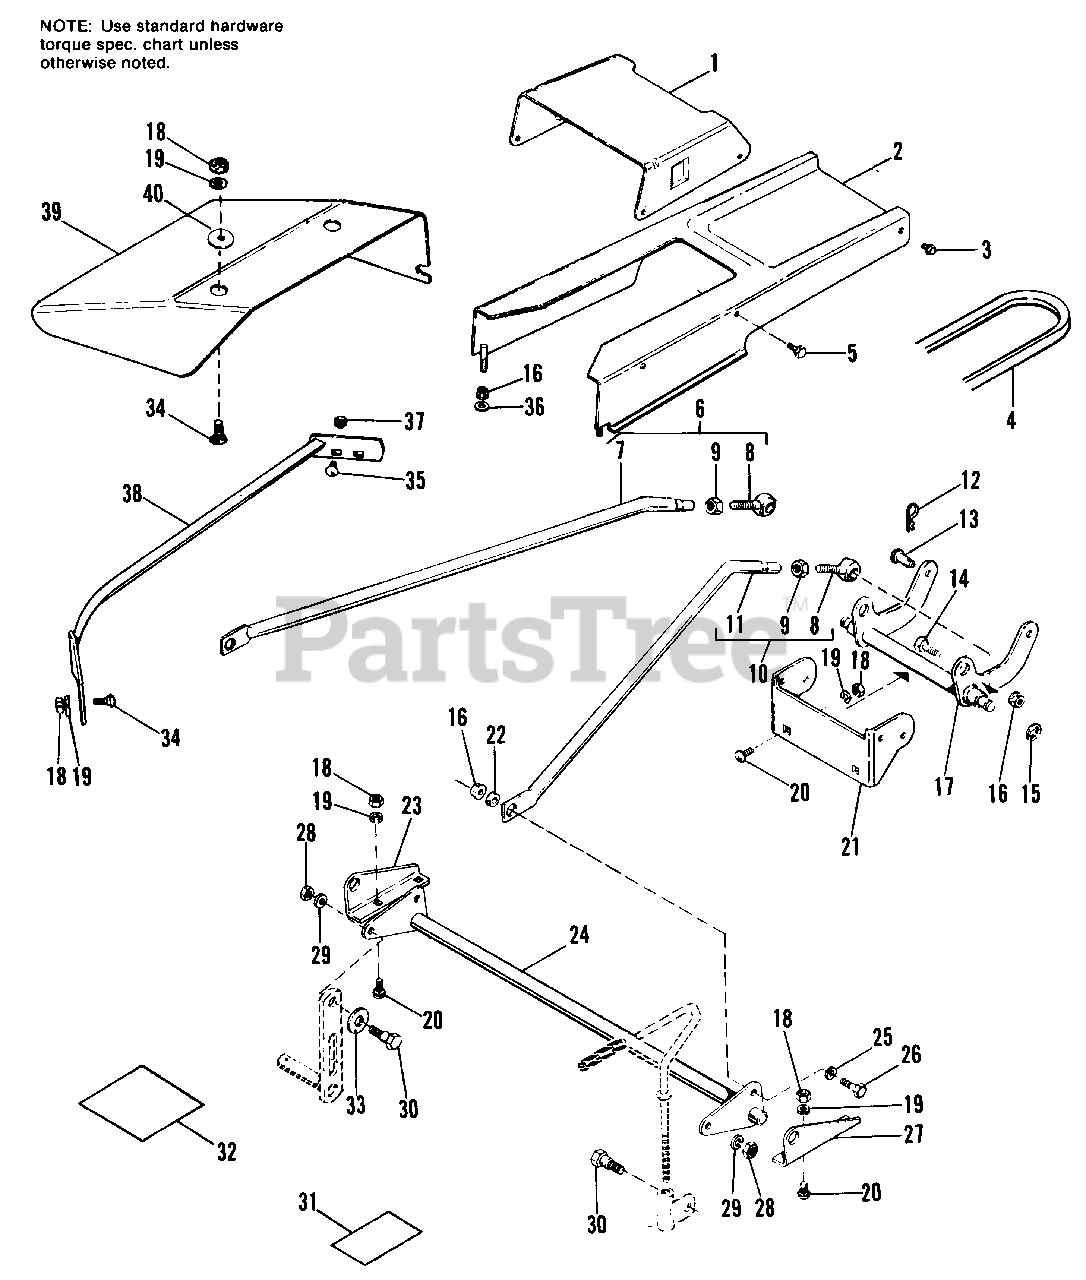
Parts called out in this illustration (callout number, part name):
1	COVER, Upper
2	COVER ASSY., Lower
3	SCREW, Hex, Washer Hd., Taptite, 3/8-16 x 1/2
4	V-BELT, 49.1"
5	SCREW, Hex, Washer Hd., Taptite, 1/4-20 x 3/8
6	ARM ASSY., Adjusting, R.H.
7	ARM, Adjusting, R.H.
9	LOCKNUT, Jam, 1/2-20
10	ARM ASSY., Adjusting, L.H.
11	ARM, Adjusting, L.H.
12	SPRING, Clip
14	BOLT, Shoulder
15	RING, Retaining
16	LOCKNUT, Hex, 3/8-16
17	ARM ASSY., Link
18	NUT, Hex, Full, 5/16-18
19	LOCKWASHER, 5/16
20	BOLT, Carriage, 5/16-18 x 5/8
21	BRACKET, Mower
23	BRACKET, Pivot, L.H.
24	ARM ASSY., Control
25	WASHER, Plain, 3/8
26	CAPSCREW, Hex Hd., 3/8-16 x 1
27	BRACKET, Pivot, R.H.
28	NUT, Hex, Full, 3/8-16
29	LOCKWASHER, 3/8
30	BOLT, Shoulder, 3/8-16 X 1.34
31	DECAL, Danger
32	DECAL, Danger
33	WASHER, Plain, 7/16
34	BOLT, Carriage, 5/16-18 x 3/4
35	BOLT, Carriage, 5/16-18 x 1/2
36	WASHER, Plain, 5/16
37	LOCKNUT, Jam, 5/16-18
38	GUARD ASSY., Stone
39	DEFLECTOR
40	WASHER
